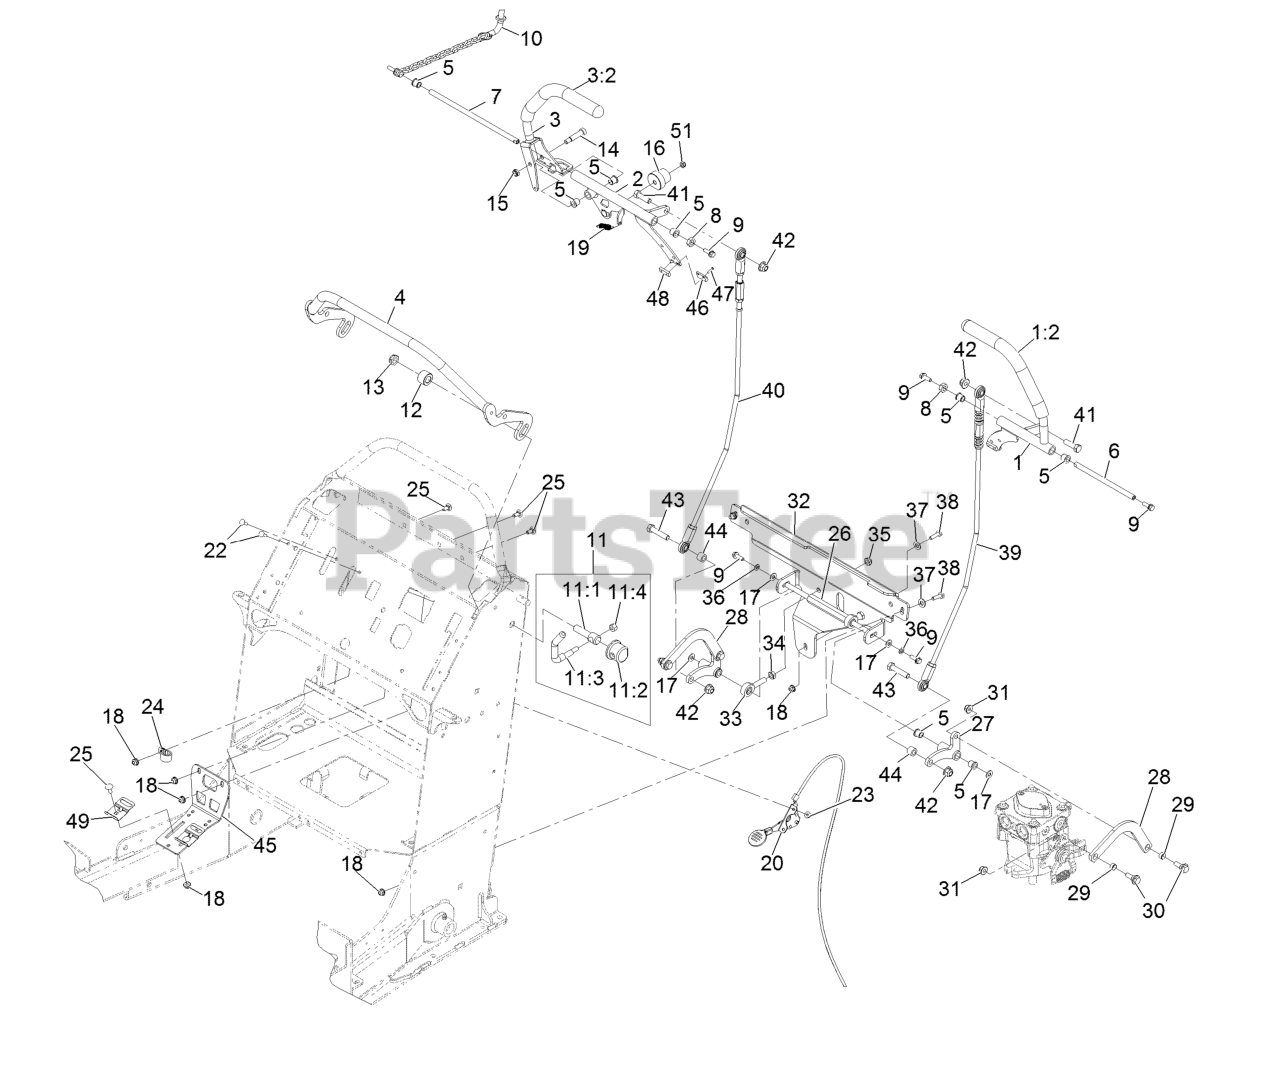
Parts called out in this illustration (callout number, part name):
1	Lever ASM, LH
1:2	Grip-Handle, Control
2	Weld, Motion Control
3	ASM, Lever W/ Grip, Rt
3:2	Grip-Handle, Control
4	Tube ASM, Front Speed Control [
5	Bearing
6	Shaft-Pivot, Motion Control
7	Shaft-Pivot, Motion Control
8	Spacer-Shaft, Drive Lever
9	Screw-Hex Flange 1/4-20 X 3/4
10	HOC Pin ASM
11	Lever ASM
11:1	Screw-Lock
11:2	Cap-Lock
11:3	Lever-Lock
11:4	Nut-Nyloc 5/16-18
12	Spacer-Clamp
13	Nut-Nyloc 1/2-13 Thin
14	Screw-Shoulder 5/16-18 X 1/2
15	Nut-Nyloc 5/16-18 Thin
17	Washer-1/4 SAE
18	Nut-Nyloc 1/4-20 Flg
19	Spring-Extension
20	Control-Throttle
22	Bolt-Carriage #10-24 X 5/8
23	Nut-Flange #10-24 Top Lock
24	Clamp-Cable
25	Bolt-Carriage 1/4-20 X 5/8
26	Shaft-Bellcrank Pivot
27	Bellcrank-Control, Motion
28	Link-Bellcrank, Pump
29	Bushing-Sleeve
30	Screw-Shoulder HHF 5/16-18 X .96
31	Nut-Nyloc 5/16-18 Flg
32	Bracket-Bellcrank
33	Balljoint
34	Nut-Jam 3/8-24
35	Nut-Nyloc 3/8-24 Thin
36	Washer-Lock 1/4
37	Washer-5/16 SAE
38	Screw-HH 1/4-20 X 7/8
39	Linkage-Tracking Control, LH
40	Linkage-Tracking Control, RH
41	Screw-HH 3/8-16 X 1 1/4
42	Nut-Nyloc 3/8-16 Flg
43	Screw-HH 3/8-16 X 1 3/4
44	Spacer-Wheel
45	Bracket, Reed Switch
46	Actuator-Switch, Reed
47	Screw-HH #4-40 X 1/2 W/Nylon
48	Plate-Tapped
49	Clamp, Reed Switch
51	Nut-Nyloc 1/4-20 Thin
